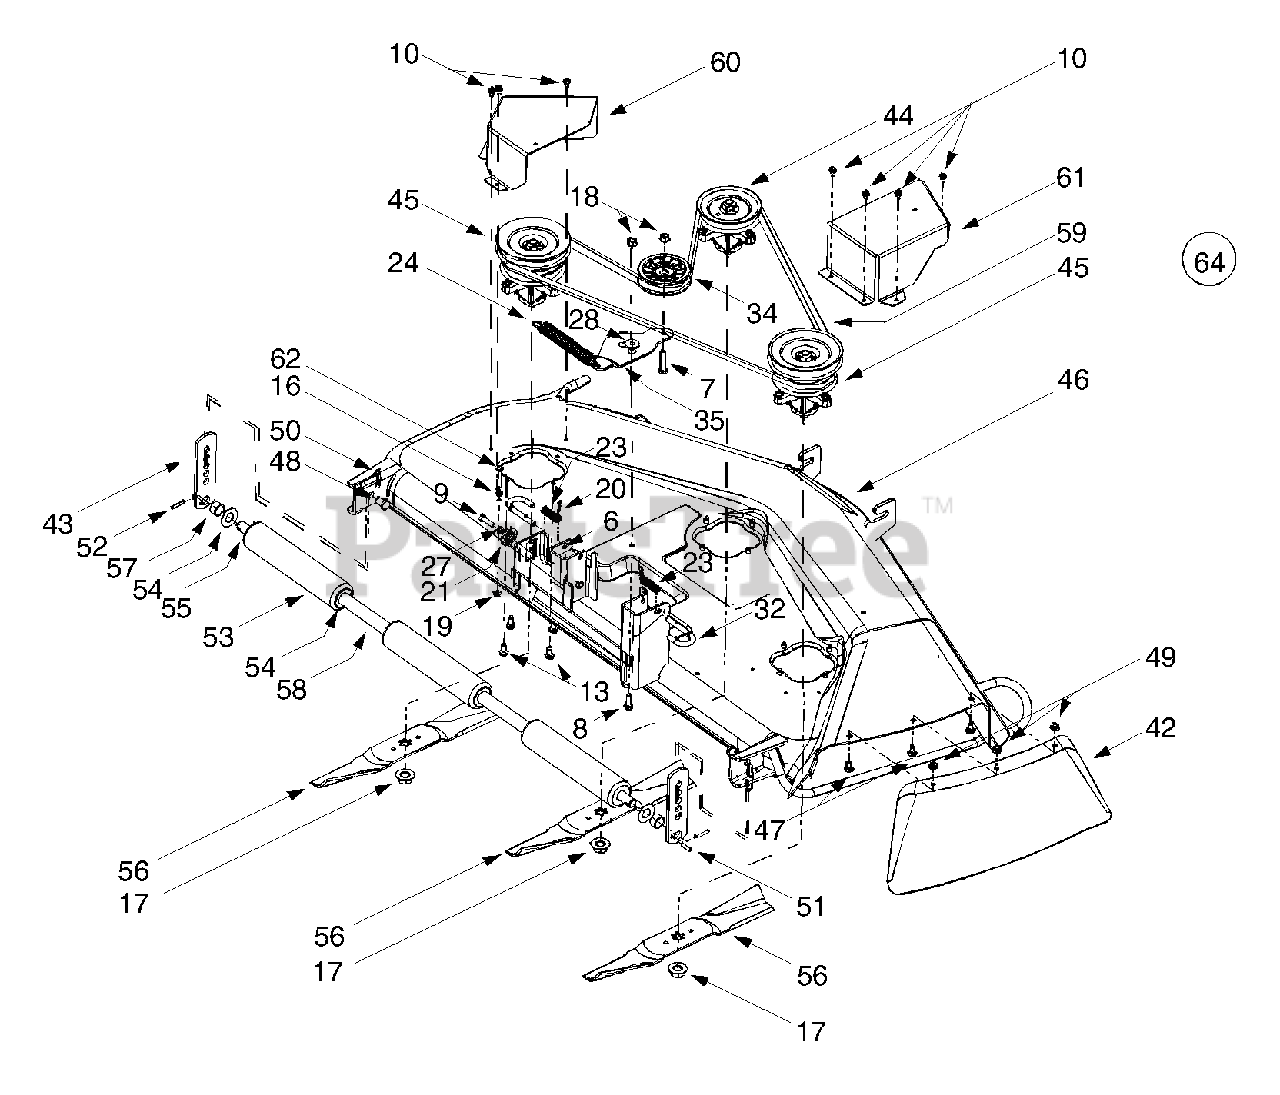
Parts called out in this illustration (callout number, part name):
6	Carriage Screw, 1/4-20 x .5
7	Hex Cap Screw, 3/8-16 x 1.75
8	Hex Cap Screw, 3/8-16 x 1.0
9	Hex Cap Screw, 5/16-18 x 1.25
10	Self Tapping Screw,1/4-20 x .5
13	Self Tapping Screw, 5/16-18 x .75
16	Center Lock Nut, 1/4-20
17	Hex Flange Nut, 5/8-18
18	Flange Lock Nut, 3/8-16
19	Hex Flange Lock Nut, 1/4-20
20	Internal Cotter Pin, .072 x 1.12
21	Deck Adjustment Gear
23	Compression Spring, .406 x .531 x 1.75
24	Extension Spring, .91 x 7.33
27	Lock Washer, 5/16
28	Shoulder Spacer, .625 x .169
32	Deck Release Pin
34	Flat Idler Pulley, 3.5 OD
44	Center Spindle Ass'y, 5 Dia. w/ Fitting
45	Double Pulley Spindle Ass'y w/ Fitting
48	Clevis Pin, .50 Dia. x .78
49	Hex Flange Lock Nut, 5/16-18
50	Click Pin, .092 x 1.64
51	Spring Pin, 1/4 Dia. x 1
52	Spring Pin, 3/16 x 1.25
54	Flat Washer, .78 x 1.59 x .06
55	Deck Roller Shaft, .75 Dia. x 47.12
56	Blade, Star Center, 17.3
57	Spacer, .752 x 1.0 x .53
